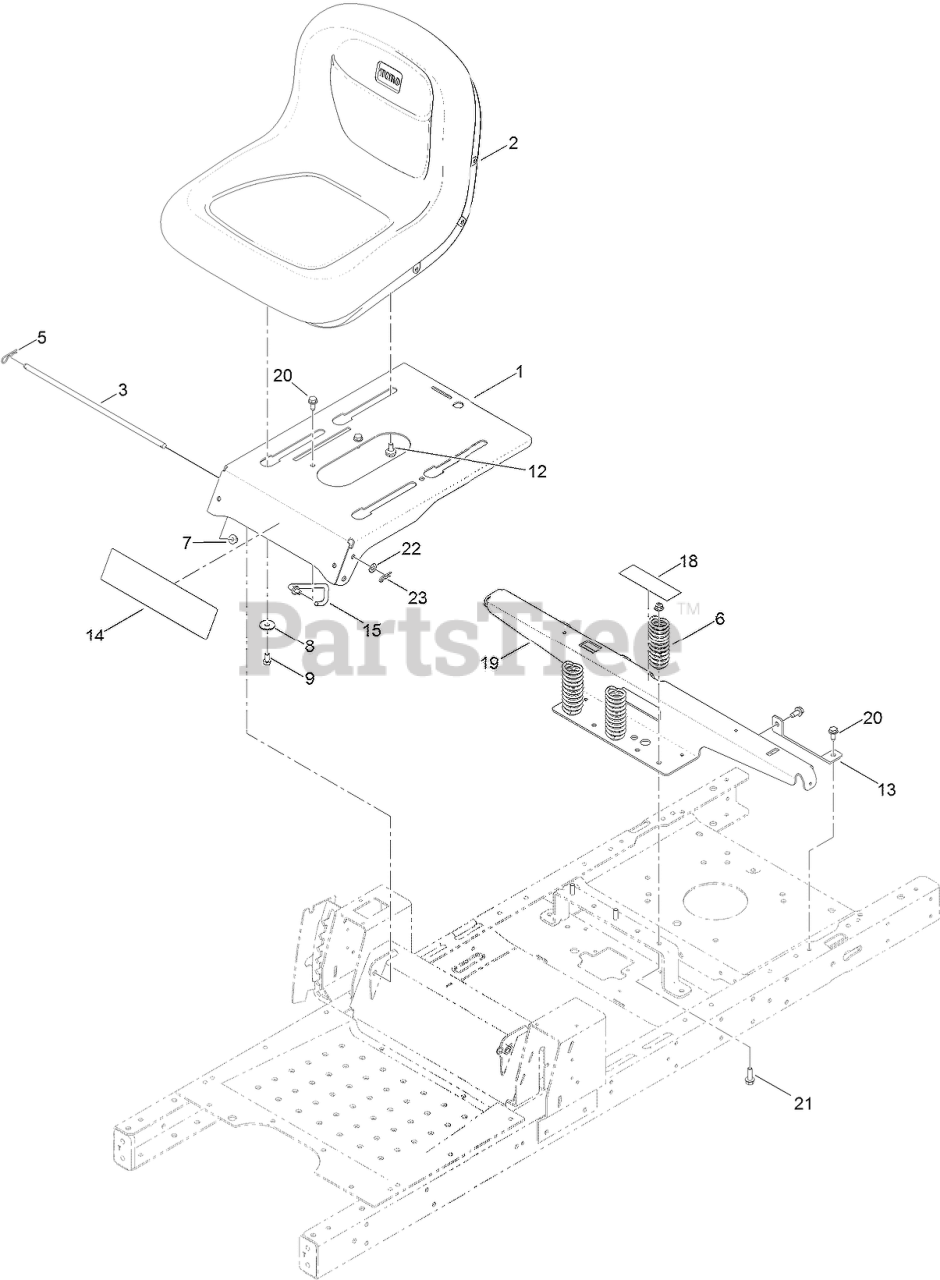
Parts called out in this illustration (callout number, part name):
1	PAN-SEAT
2	SEAT-15 INCH
3	ROD-PIVOT, NARROW
5	PIN-COTTER
6	SPRING-COMPRESSION
7	NUT-HF, NI
8	WASHER-PIVOT
9	SCREW-HH
12	BOLT-SHOULDER
13	SUPPORT-TANK, REAR
14	DECAL-TIMECUTTER
15	STOP-SEAT
18	DECAL-SERVICE, CE
19	SUPPORT-POD
20	SCREW-HWHTF
21	SCREW-HHF
22	WASHER-PLAIN
23	PIN-COTTER
